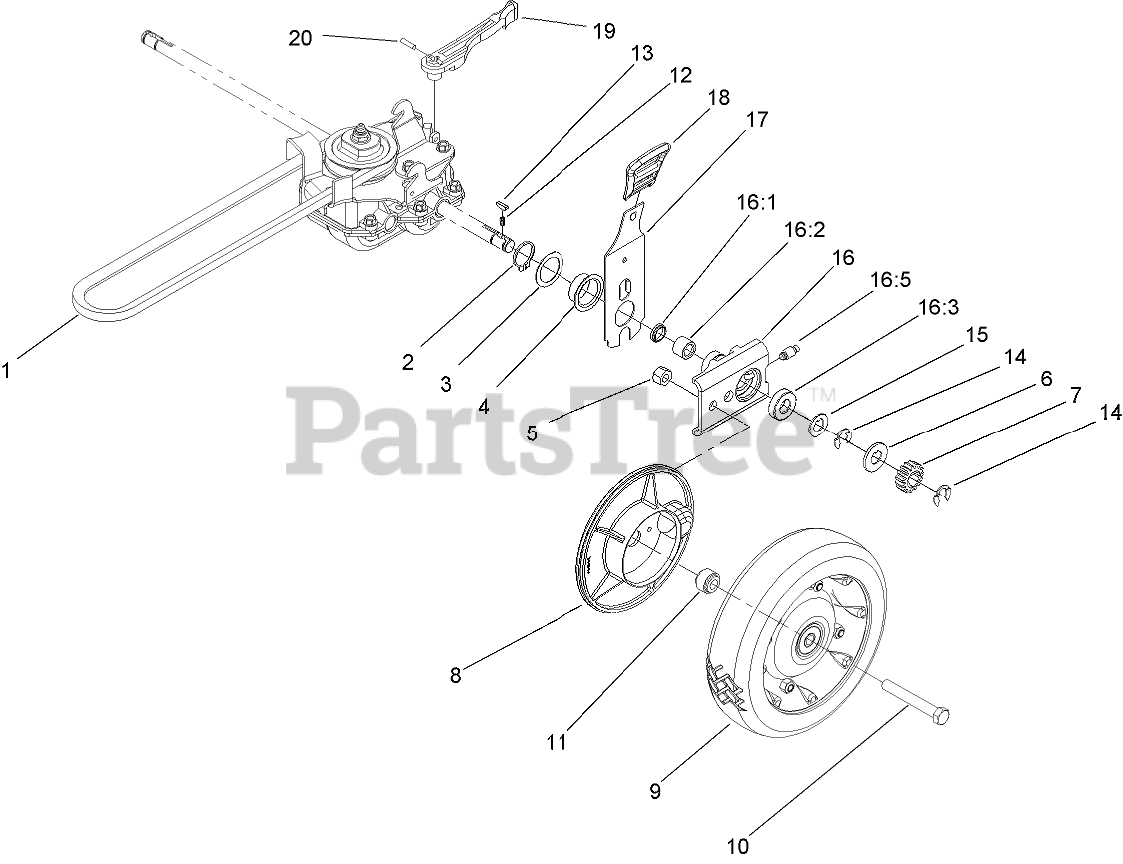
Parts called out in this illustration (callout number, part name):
1	V-BELT
2	RING-RETAINING
3	WASHER
4	CAP-END
5	NUT-LOCK, CONE
6	WASHER-THRUST, OUTER
7	GEAR-PINION
8	COVER-WHEEL
9	Wheel And Tire ASM
10	SCREW-HH
11	SPACER-COVER, WHEEL
12	SPRING-COMPRESSION
14	RING-RETAINING
15	WASHER-THRUST, OUTER
16	PIVOT ARM ASM
16:1	SEAL-OIL
16:2	BEARING-ROLLER
16:3	BEARING-WHEEL
17	REAR SPRING ARM ASM
18	KNOB-HOC
19	LEVER-SHIFT
20	PIN-COIL
